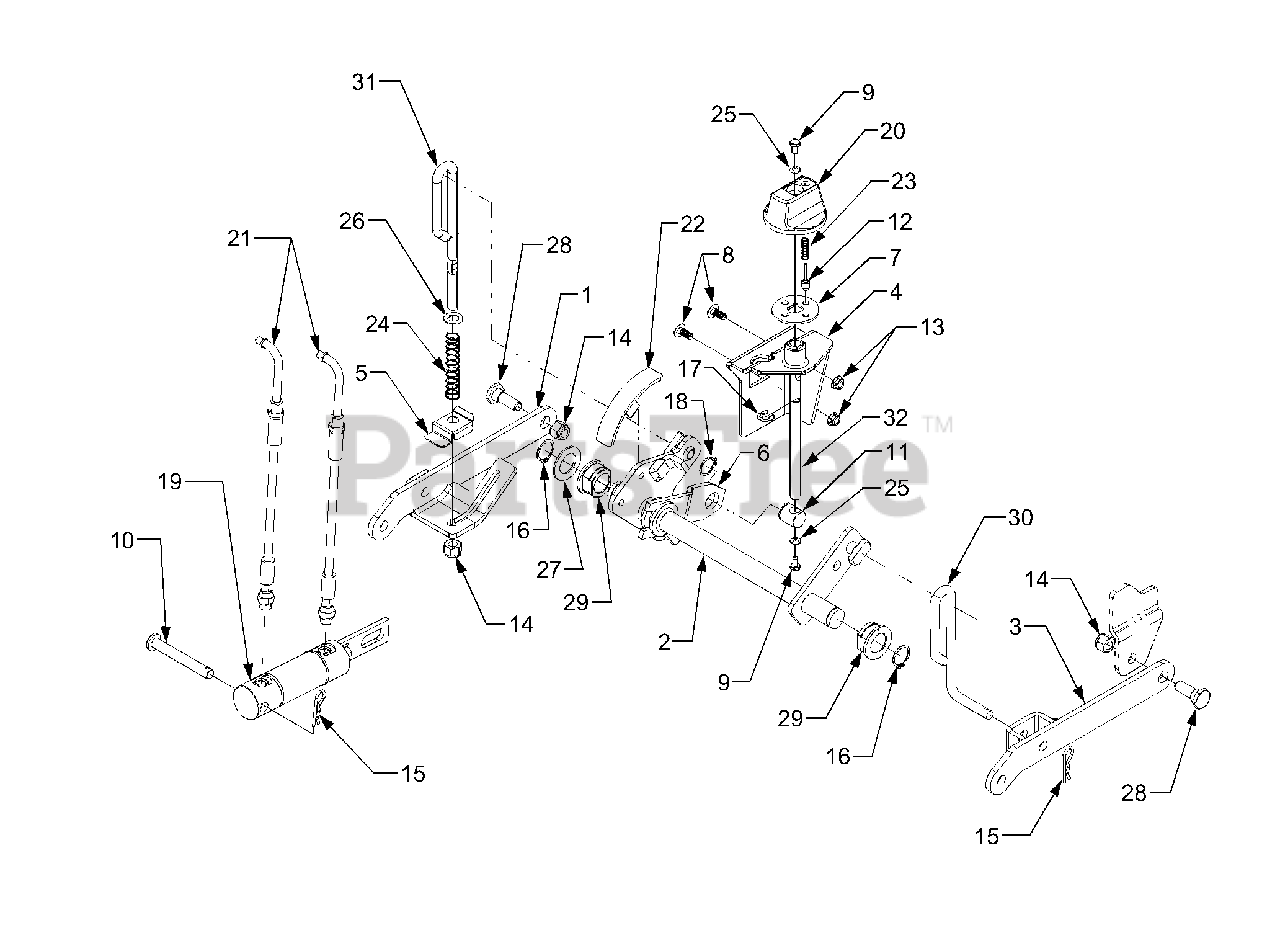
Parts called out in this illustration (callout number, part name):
1	Link, LH Lift
4	Bracket, Downstop
5	Stop Bracket, Lift Rod
6	Arm, Downstop
7	Disk, Detent
8	Bolt, Carriage, 3/8-16 x .75
9	Screw, Hex Cap, 1/4-20 x .5 GR5
10	Pin, Clevis, .5 x 3.75
11	Ferrule, Adjustment
12	Pin, Detent Plunger
13	Nut, Flange Lock, 3/8-16 GR5
14	Nut, Hex Lock, 1/2-13
15	Pin, Internal Cotter
16	Snap Ring, 1.0 Dia. Shaft
17	Ring, 'E' Retaining, .5 Dia
18	Snap Ring, .875 Dia. Shaft
19	Cylinder, Center Lift
20	Knob
21	Hose, Lift
22	Indicator, Lift Position
23	Spring, Compression
24	Spring, Compression
25	Washer, Flat, .281 x .5 x .063
26	Washer, Flat, .536 x .93 x .050
27	Washer Flat, 1.0 x 1.7 x .10
28	Shoulder Screw
29	Bearing, Flange w/Flats
30	Rod, RH Lift
31	Rod, LH Lift
32	Screw, Adjustment
